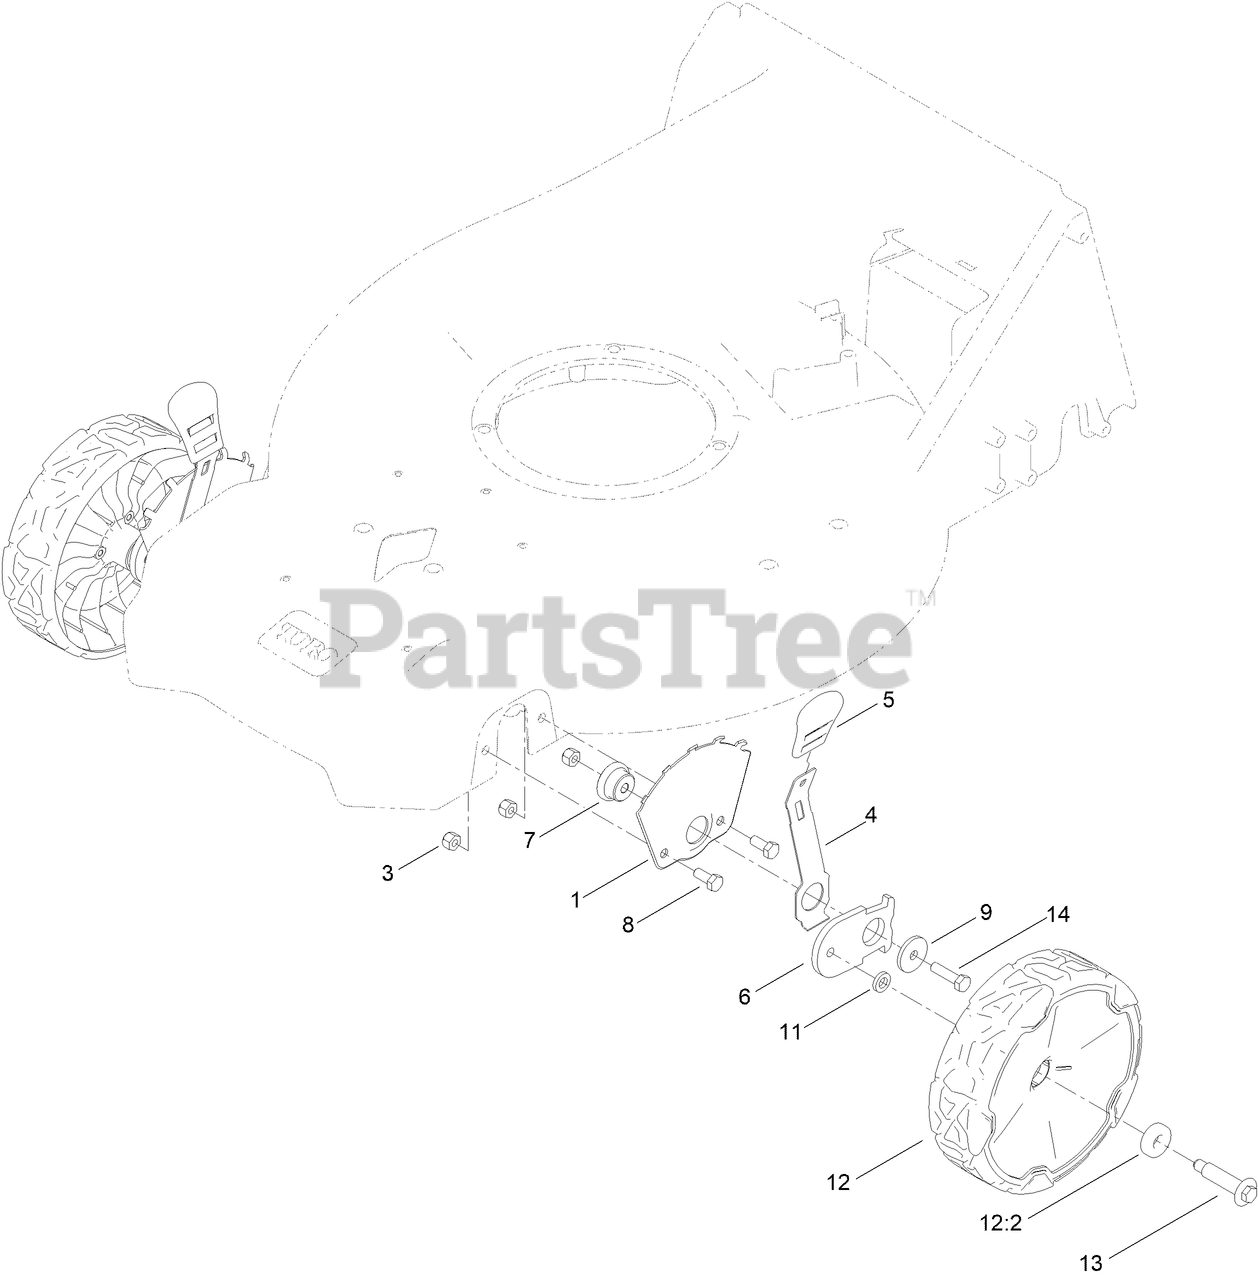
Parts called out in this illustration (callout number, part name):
1	PLATE-HOC,FRONT FSVQ WEDNESDAY
3	NUT-LOCK, NI
4	ARM-SPRING
5	KNOB-HOC
6	ARM-PIVOT, FRONT
7	BUSHING-MOUNT, HOC
8	SCREW-HH
9	WASHER-FLAT
11	WASHER-WHEEL BOLT
12	ASM-WHEEL, 8" (BEARINGS)
12:2	BEARING-WHEEL
13	BOLT-SHOULDER
14	SCREW-HH
